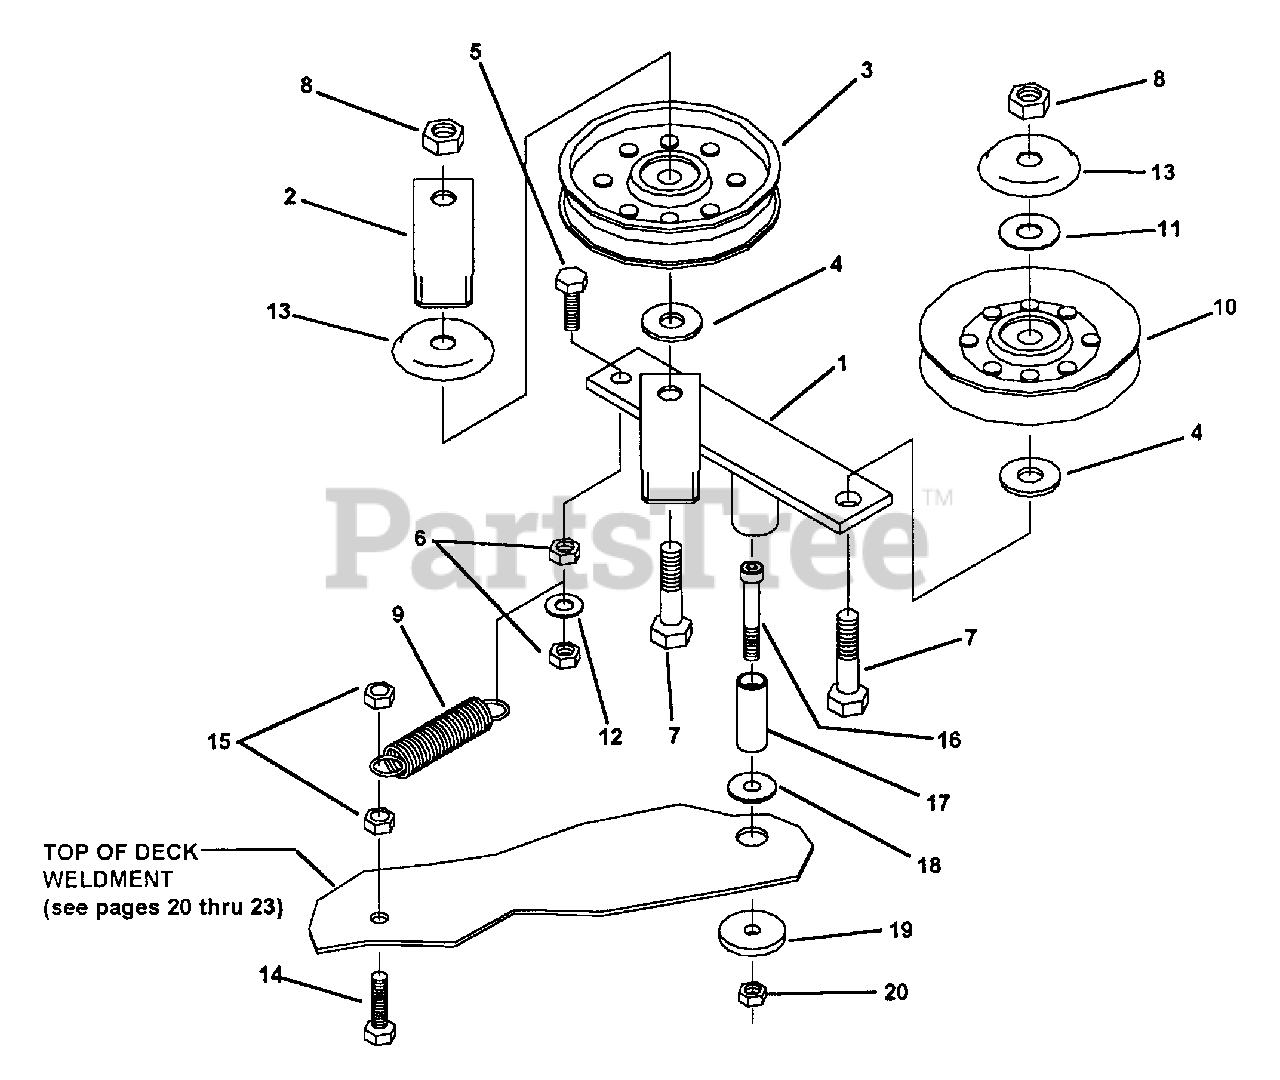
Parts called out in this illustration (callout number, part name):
1	DOUBLE IDLER WELDMENT (w/bushing)
2	PLATE, BELT STOP
3	PULLEY, FLAT IDLER 1/2 BORE, 4" O,D,
4	WASHER, FLAT STD. 1/2"
5	BOLT, 3/8-24 X 1-1/4" GR. 5
6	NUT, 3/8-24, M-F LOCKNUT
7	BOLT, 1/2-13 X 2", GR.5
8	NUT, 1/2-13, STOVER
9	SPRING, EXTENSION, 3/4 X 4" O.A.L.
10	PULLEY, V-IDLER, 1/2 BORE, 4-3/8 O.D.
11	WASHER, 1/2" TYPE B NARROW
12	WASHER, FLAT STD. 3/8"
13	WASHER, BEARING CAP
14	BOLT, 3/8-24 X 1-1/4" GR.5
15	NUT, 3/8-24, M-F LOCKNUT
16	BOLT, 5/16-18 X 2-1\4" SOC. HD. GR. 8
17	IDLER MOUNTING PIN
18	BUSHING, IDLER PIN MTG.
20	NUT, 5/16-18, STOVER
